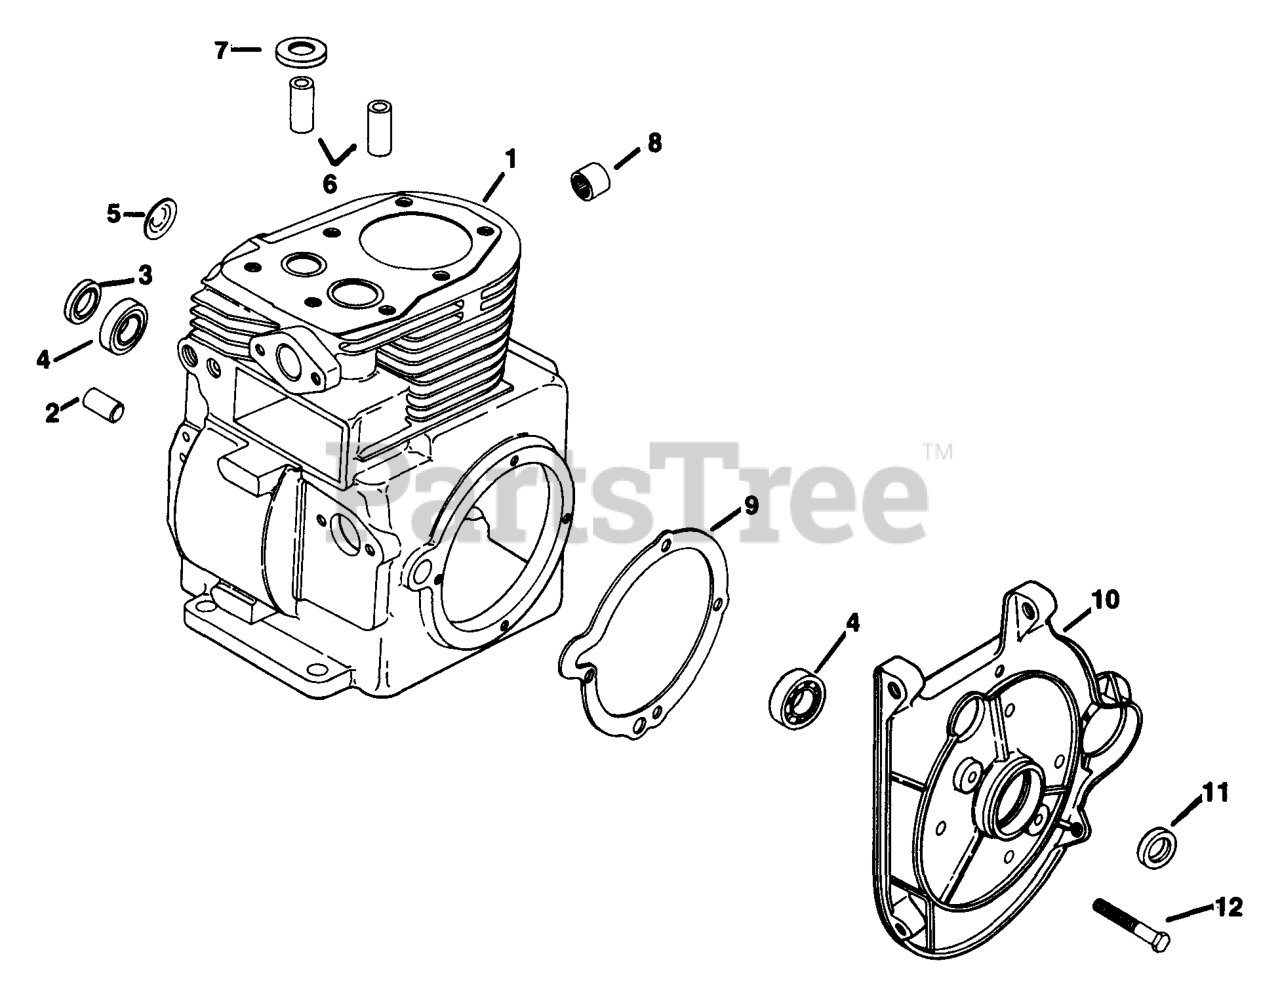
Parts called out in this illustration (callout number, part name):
1	Cylinder Block
4	BEARING - DISCONTINUED
5	PLUG, WELCH EXPANSION
7	INSERT - DISCONTINUED
8	BEARING
10	PLATE - DISCONTINUED
